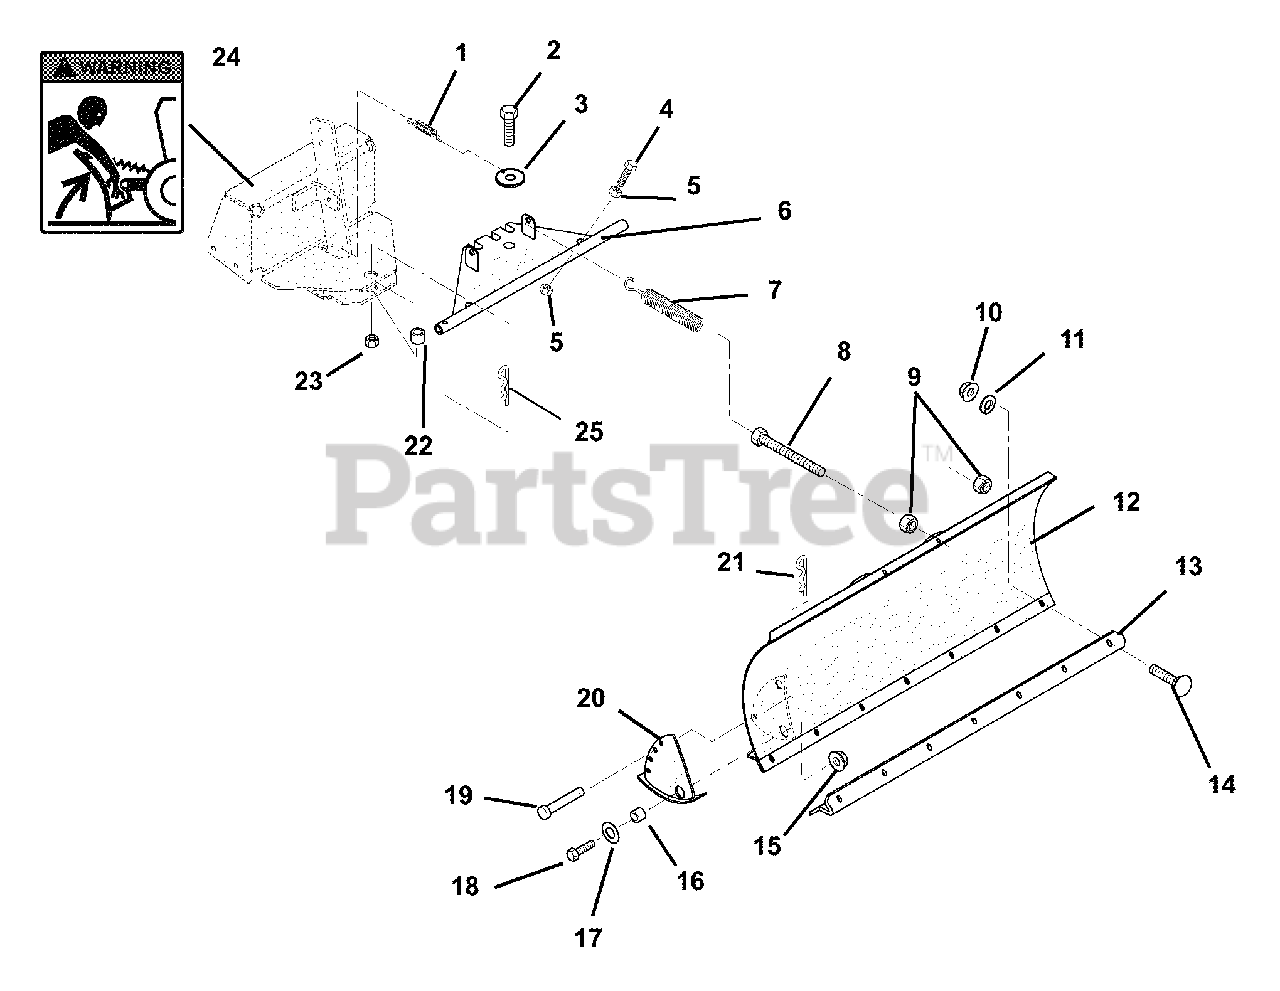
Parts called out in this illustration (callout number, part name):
1	Spring, Latch Agri-Fab Part #732-0360
2	Bolt-Hex .75-10 x 3.00 Grade 5
3	Washer, .38 Special Agri-Fab Part# 736-0306
4	Bolt-Hex .50-13 x 2.00 Grade 5
5	Nut-Hex .50-13
6	Weldment, Pivot Plate Agri-Fab Part# 05677
7	Spring, Blade Adjustment Agri-Fab Part# 732-0359
8	Bolt, Hex .38-16 x 4.00 Full Threaded
9	Nut-Hex .38-16
10	Nut-Locking-Center .31-18
11	Washer-Locking .31 x .078 Regular
12	Weldment, 54" Blade (Agri-fab) Agri-Fab Part# 05674
13	Plate, Wear Agri-Fab Part #05687
14	Bolt-Round Head Square Neck .31-18 x .75 Grade 5
15	Nut-Locking-Center .38-16
16	Bushing, Skid Pivot Agri-Fab Part# 750-0437
17	Washer-Flat-Steel .406 x .812 x .065
18	Bolt-Hex, .38-16 x 1.00 Grade 5
19	Pin, Clevis .312 x 1
20	Skid, 54" Blade Agri-Fab Part #05655
21	Pin-Hair Internal .08 x .18 x 1.18
22	Spacer, .753 x 1.00 x 1.60
23	Nut-Locking-Jam-Nylon .75-10
24	Decal, Pinch Point
25	Internal Hair Pin, .15 x 2.937
